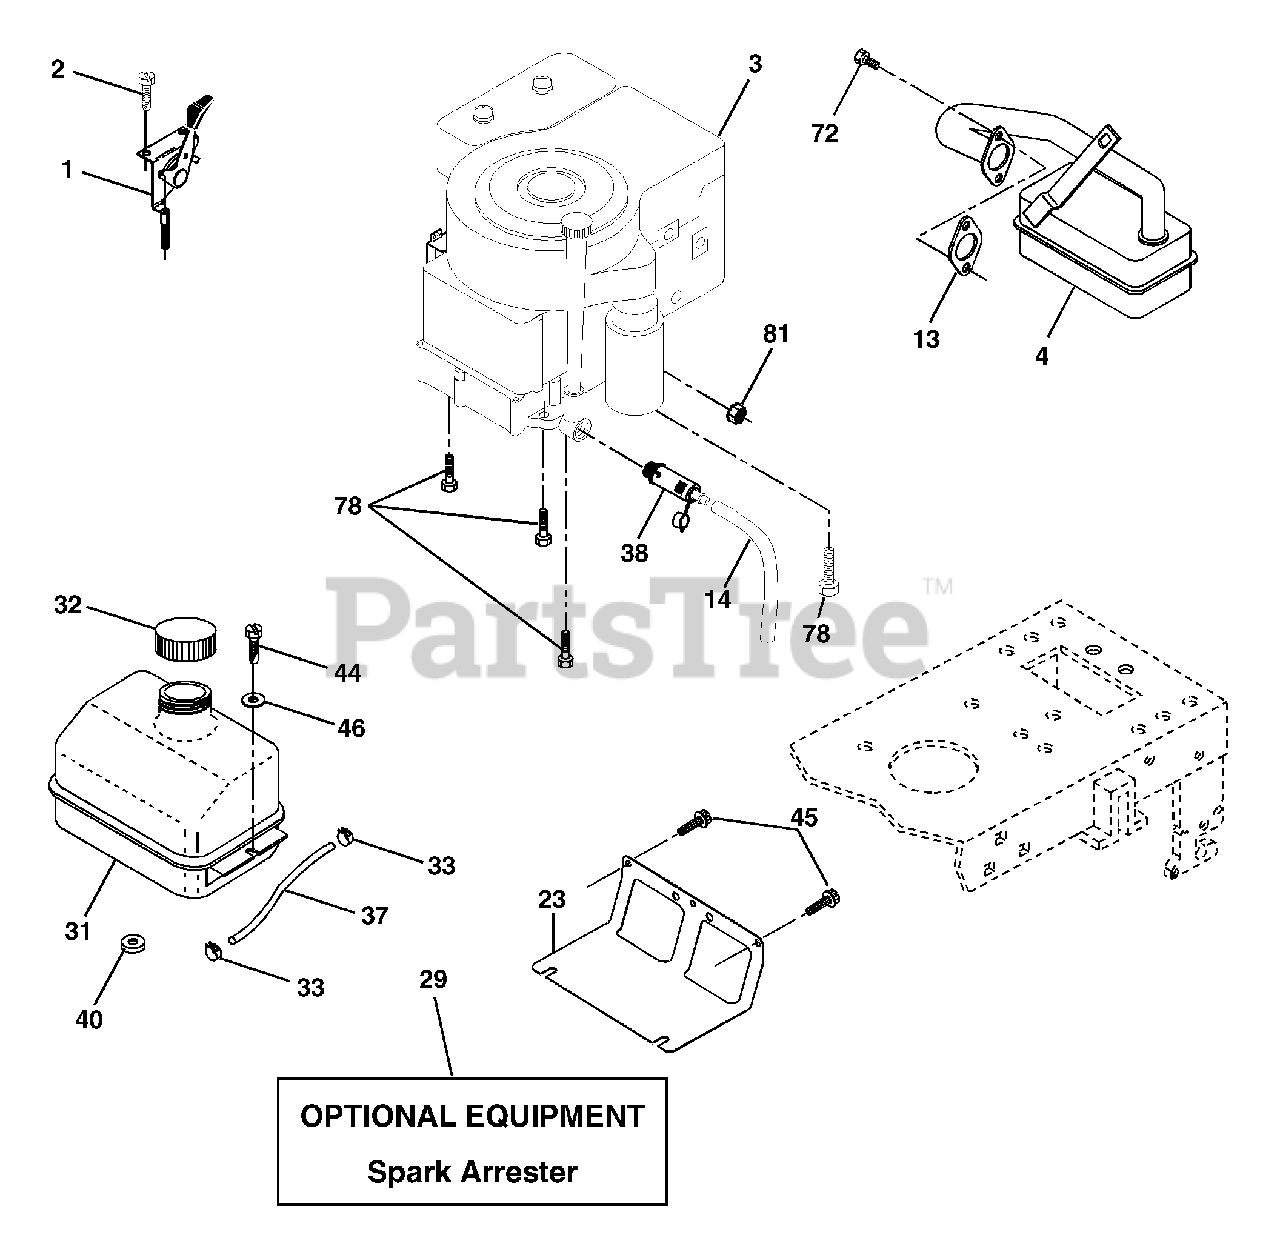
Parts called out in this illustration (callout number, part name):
1	Control Th/ch Flag
2	Screw Hex Thd Cut 1/4-20 x 1/2
13	Gasket Eng
14	Tube Drain Oil Easy
23	Shield Brn/Dbr Guard
29	Kit Spark Arrestor (Flat Scrn)
31	Tank Fuel Front
32	Cap Asm Fuel W/sym Vented
33	Clamp Hose Black
37	Line Fuel 20"
38	Plug Drain Oil Easy
40	Bushing Snap Nyl Blk Fuel Line
44	Screw Hexwsh Thdrol 1/4-20 x 3/4
45	Screw Hexwsh Thdr 3/8-16 x 3/4
46	Washer 9/32 x 7/8 x 16 Ga.
72	Screw Socket Head 5/16-18 x 1
78	Screw 3/8-16 x 1-1/4 SMGML
81	Nut Keps Hex 1/4-20 unc
